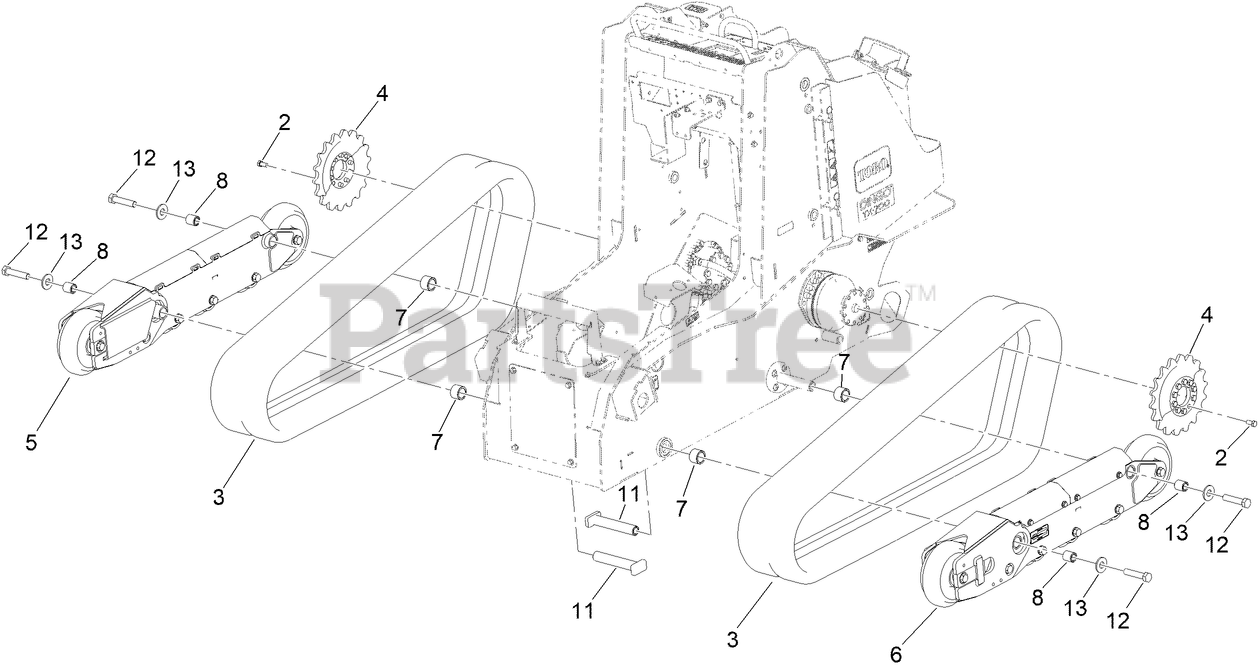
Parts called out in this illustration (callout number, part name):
2	SCREW-HH
3	TRACK-WIDE,
4	SPROCKET-DRIVE
5	TRACK ASM-RH
6	TRACK ASM-LH
7	SPACER-TRACK
8	SLEEVE-TRACK
11	PIN-TRACK
12	SCREW-HH
13	WASHER
